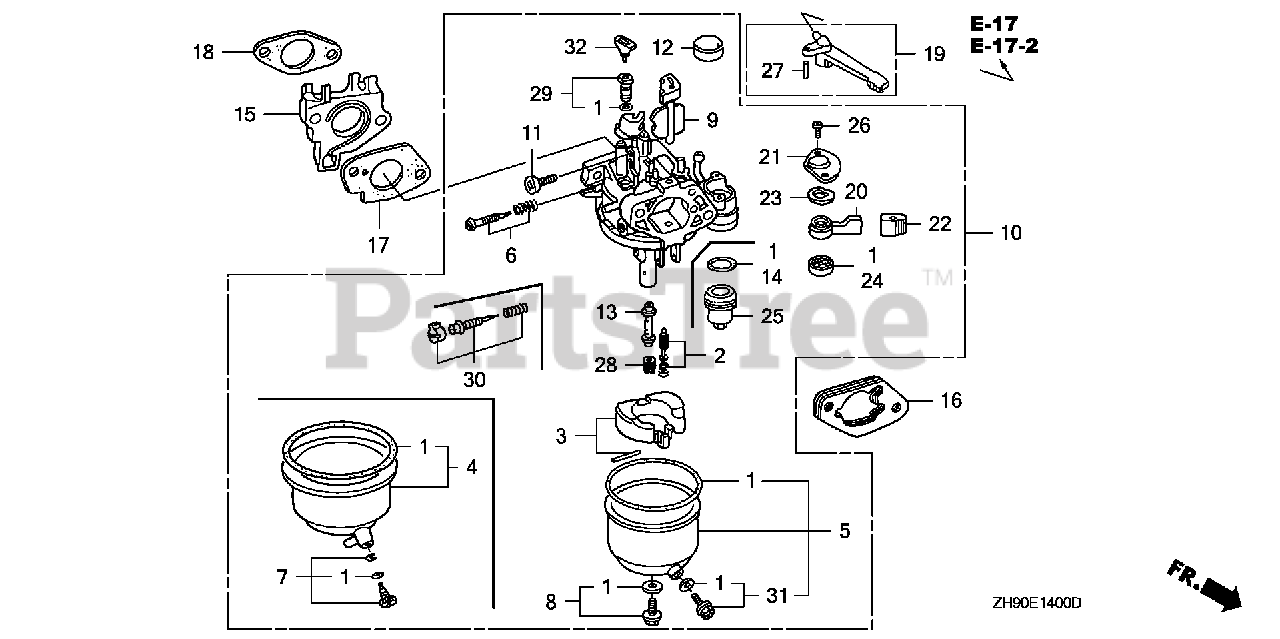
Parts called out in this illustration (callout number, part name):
1	GASKET SET (INCLUDE 16173-001-004) (INCLUDES 16173-001-004)
2	VALVE SET, FLOAT
3	FLOAT SET
5	CHAMBER SET, FLOAT
8	SCREW SET B
8	SCREW SET
9	CHOKE SET
10	CARBURETOR ASSY. (BE75B B/C)
11	SCREW, THROTTLE STOP
13	NOZZLE, MAIN (CARBURETOR NO.)
14	GASKET, FUEL STRAINER CUP
15	INSULATOR, CARBURETOR
16	SPACER, CARBURETOR
17	GASKET, CARBURETOR
18	GASKET, INSULATOR
19	LEVER, CHOKE (STD)
20	LEVER, VALVE
21	PLATE, LEVER SETTING (CARBURETOR NO.)
23	SPRING, PETCOCK LEVER (CARBURETOR NO.)
24	GASKET, VALVE
25	CUP, FUEL STRAINER
26	SCREW, PAN (3X6)
27	PIN, SPRING (2X12)
28	JET, MAIN (#80)
28	JET, MAIN (#82)
28	JET, MAIN (#85) Use up to Engine SN BE81B B.
29	JET SET, PILOT (#40) (ADVENTURE GREEN) (CARBURETOR NO.)
30	SCREW SET (Honda Code 4219879). (CARBURETOR NO.)
31	SCREW SET, DRAIN (Honda Code 1672187). (CARBURETOR NO.)
32	COLLAR, SET
